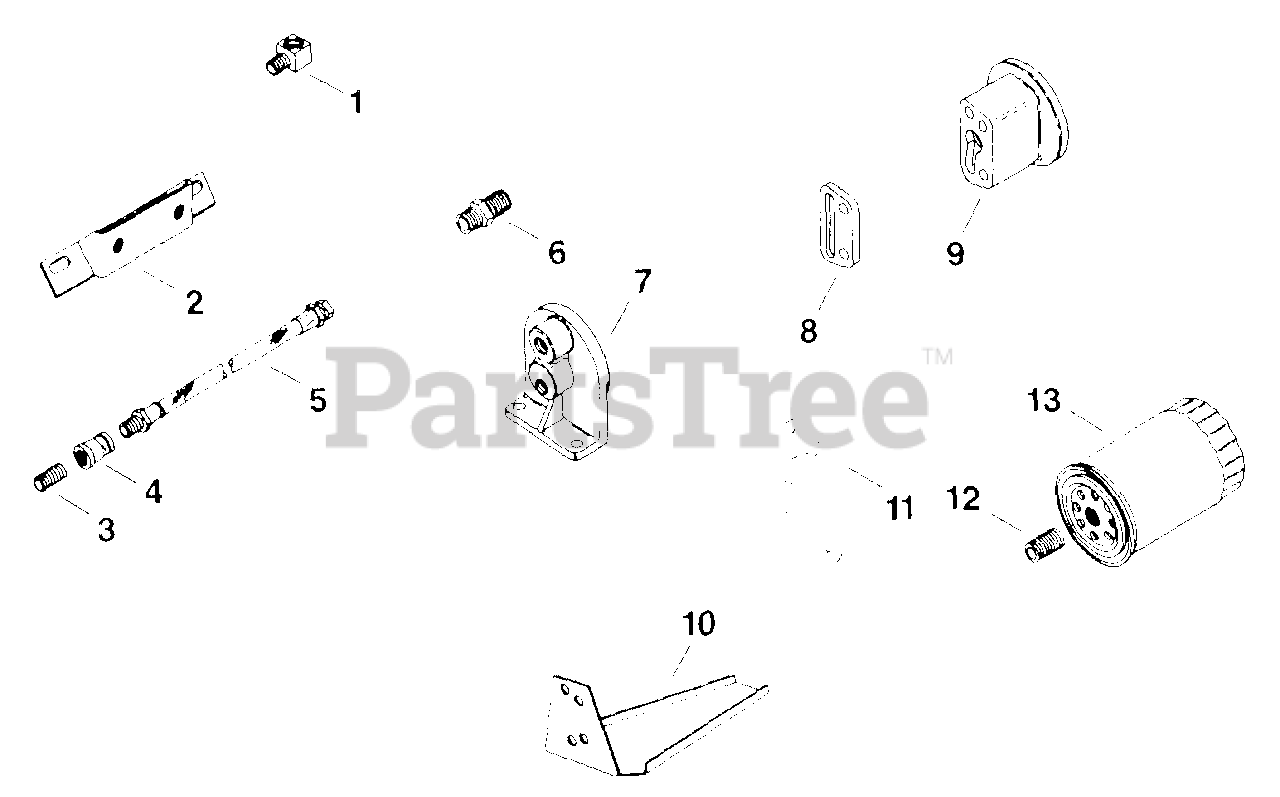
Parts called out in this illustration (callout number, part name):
9	ADAPTER - USE 48 029 02
11	GASKET - USE 48 041 03
13	FILTER, OIL
